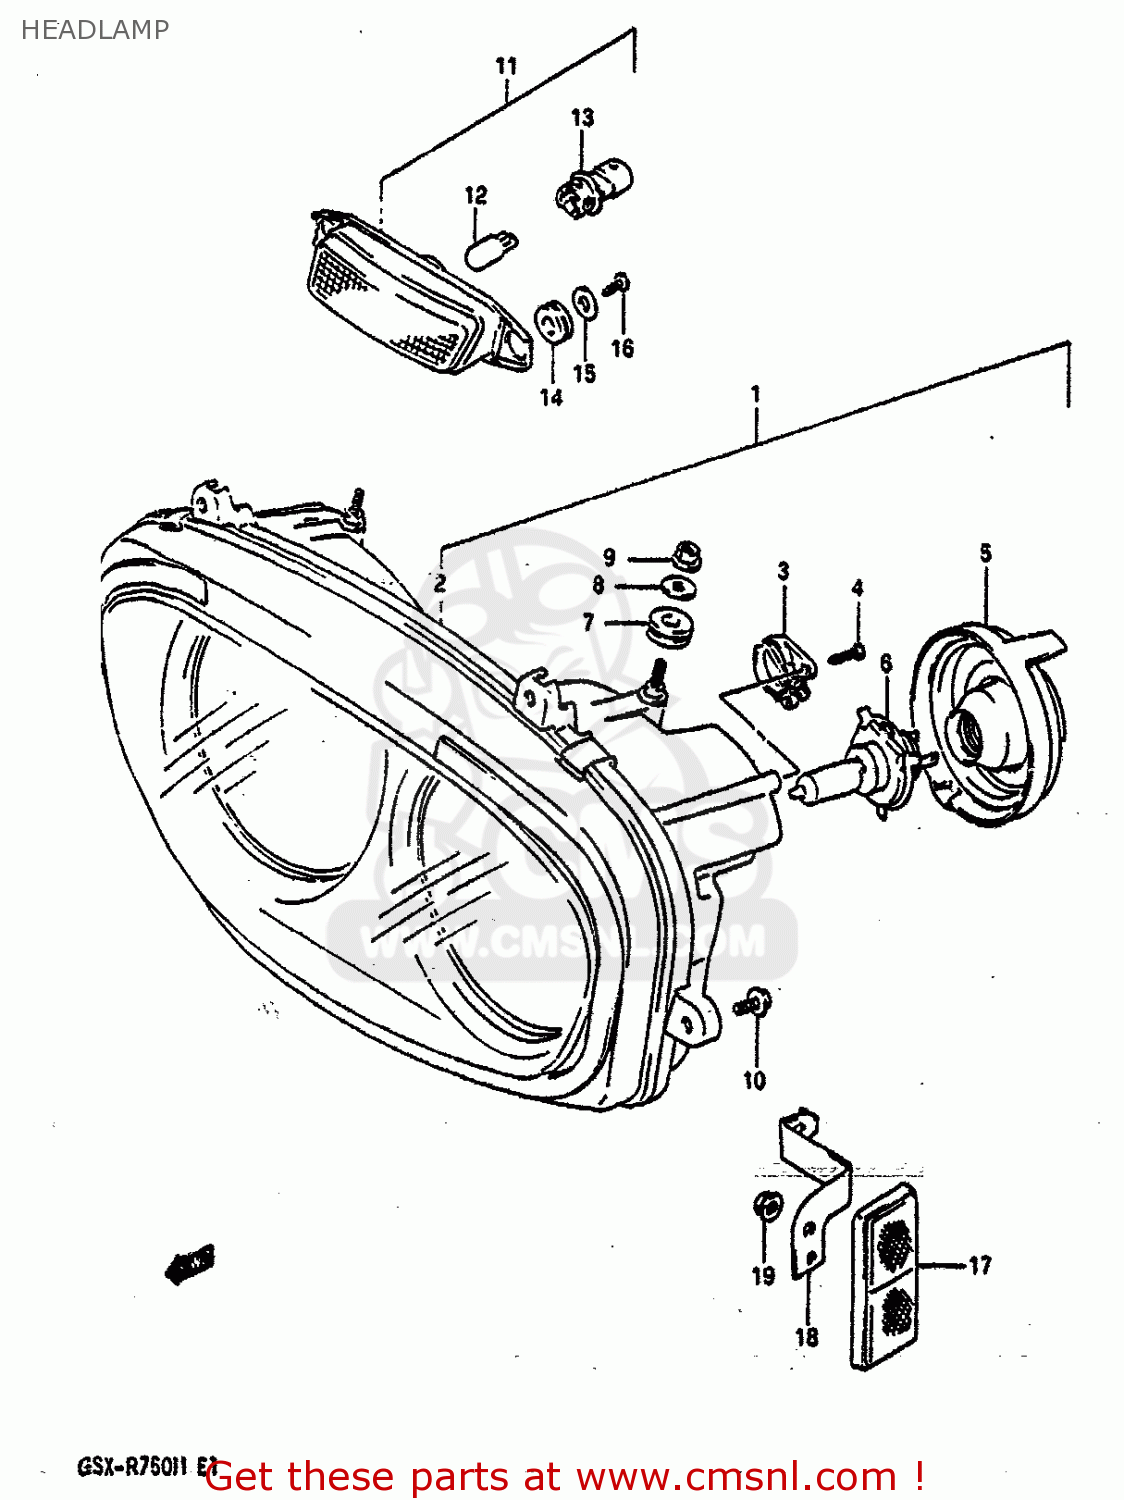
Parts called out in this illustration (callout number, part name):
1	HEADLAMP ASSY
2	UNIT,HEADLAMP
3	GEAR UNIT ASSY,LWR
4	SCREW
5	COVER,SOCKET
6	BULB(12V60/55W,H4)
7	GROMMET
8	WASHER
9	NUT 6MM
10	SCREW
11	LAMP ASSEMBLY,FRONT POSITION
12	BULB(12V5W)
13	SOCKET ASSY
14	CUSHION
15	WASHER
16	SCREW
17	REFLECTOR,REFLEX FR
18	BRACKET,FR SIDE RR,R
19	NUT
